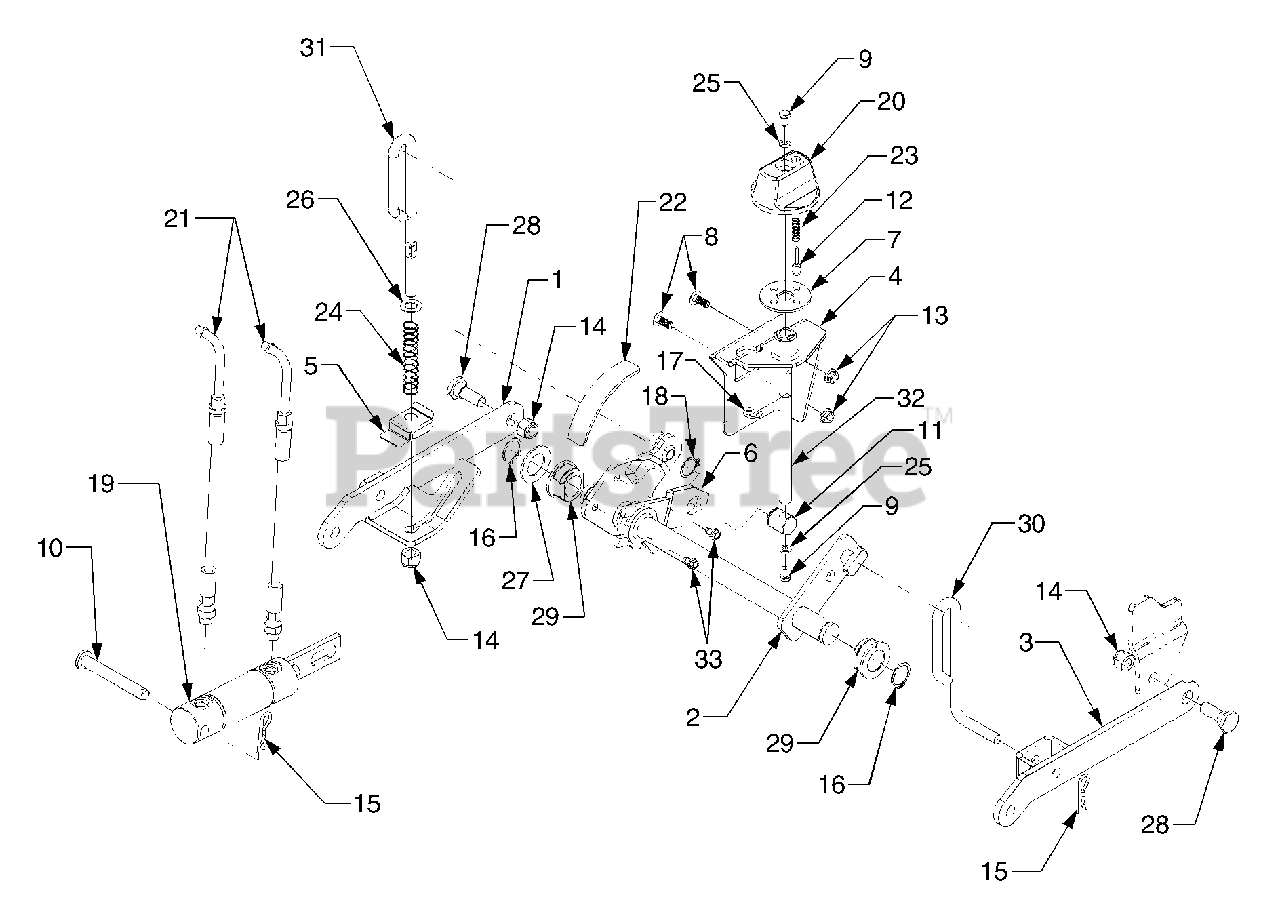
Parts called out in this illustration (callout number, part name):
1	Link, LH Lift
4	Bracket, Downstop
5	Stop Bracket, Lift Rod
6	Arm, Downstop
7	Disk, Detent
8	Bolt , Carriage, 3/8-16 x .7 5
9	Screw, Hex Cap, 1/4-20 x .5 GR5
10	Pin, Clevis, .5 x 3.75
11	Ferrule, Adjustment
12	Pin, Detent Plunger
13	Nut, Flange Lock, 3/8-16G R5
14	Nut, Hex Lock, 1/2-13
15	Pin, Internal Cotter
16	Snap Ring, 1.0 Dia. Shaft
17	Ring, 'E' Retaining, .5 Dia.
18	Snap Ring, .875 Dia. Shaft
19	Cylinder, Center Lift
20	Knob
21	Hose, Lift
22	Indicator, Lift Position
23	Spring, Compression
24	Spring, Compression
25	Washer, Flat, .281 x .5 x .063
26	Washer, Flat, .536 x .93 x .0 50
27	Washer. Flat, 1.0x 1.7 x .10
28	Shoulder Screw
29	Bearing, Flange w/Flats
30	Rod, RH Lift
31	Rod, LH Lift
32	Screw, Adjustment
33	Screw, Hex Wash. Hd. Tapp 1/4-20 x .5
